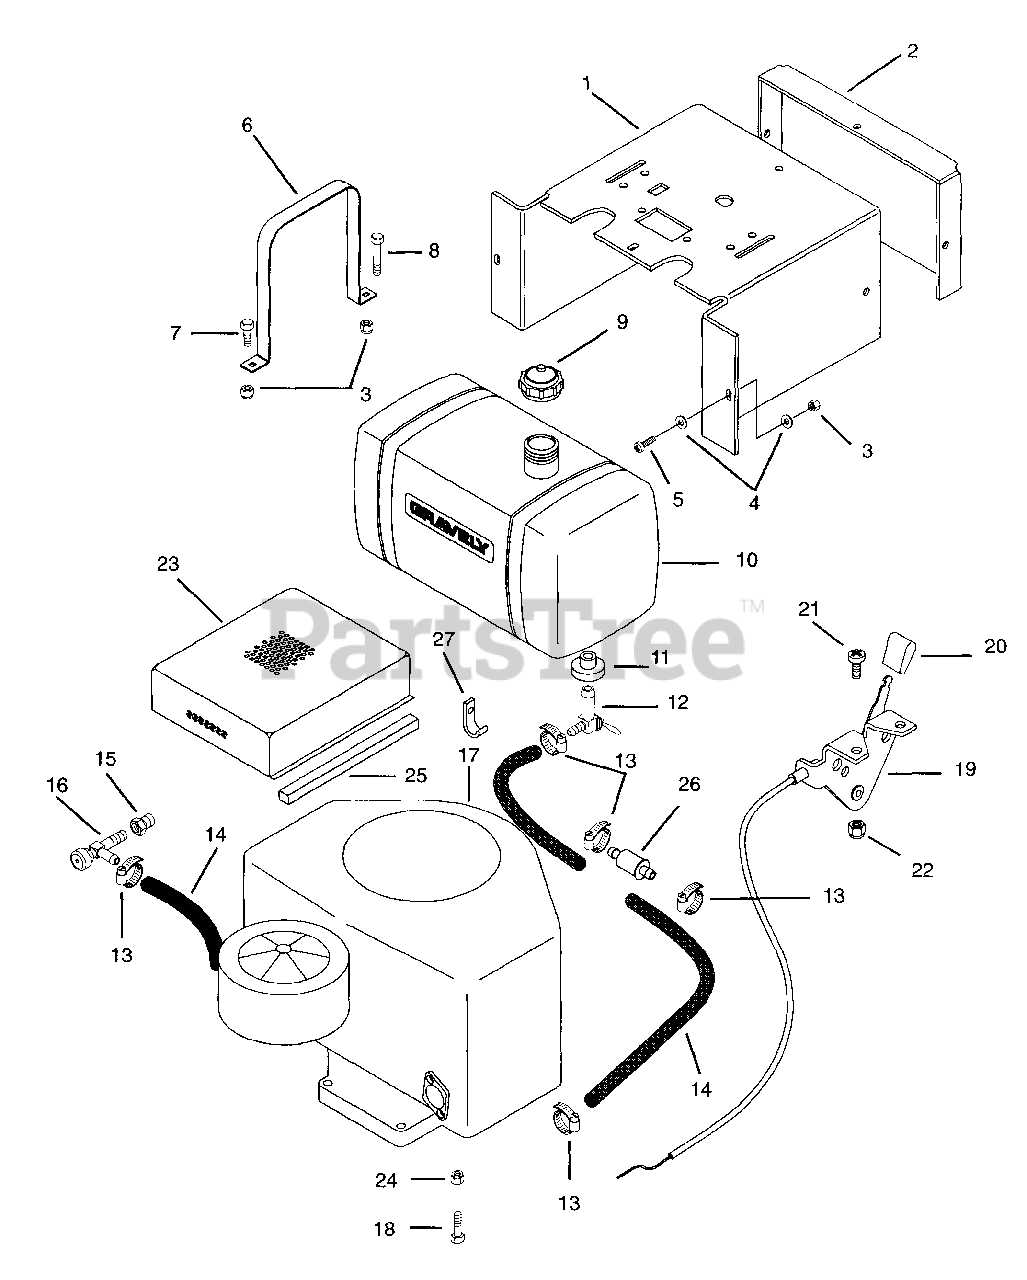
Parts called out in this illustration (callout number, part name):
1	Panel-Silkscreen
2	Cover-Instrument Panel
3	Nut-Locking-Center .25-20
4	Washer-Flat-Steel .281 x .620 x .065
5	Screw-Machine-Hex-Washer-Head .25-20 x .75
6	Strap-Fuel Tank
7	Bolt-Hex .25-20 x .75 Grade 5
8	Bolt-Hex .25-20 x 1.00 Grade 5
9	Cap-Fuel Tank
10	Tank-Fuel PM 200
11	Bushing
12	Fitting-Tank
13	Hose Clamp
14	Gas Line-Bulk
15	Adapter-Oil Drain
16	Cock-Oil Drain
17	Engine-Kohler CV20
17	Engine-Kawasaki
18	Screw-Tapping-Hex-Washer-Head .375-16 x 1.0
18	Bolt-Hex M8 x 1.25 x 25 Grade 8
18	Bolt-Hex M8 x 1.25 x 55
19	Assembly-Throttle Control
19	Assembly-Choke-Kohler
20	Knob
21	Screw-Machine-Hex-Washer-Head 10-24 x .50
22	Nut-Locking-Nylon w/Insert 10-24
23	Weldment-Pre-Cleaner Screen
24	Nut-Locking-Center M8-1.25
25	Pad-Pre-Cleaner Screen
26	Filter-Fuel
